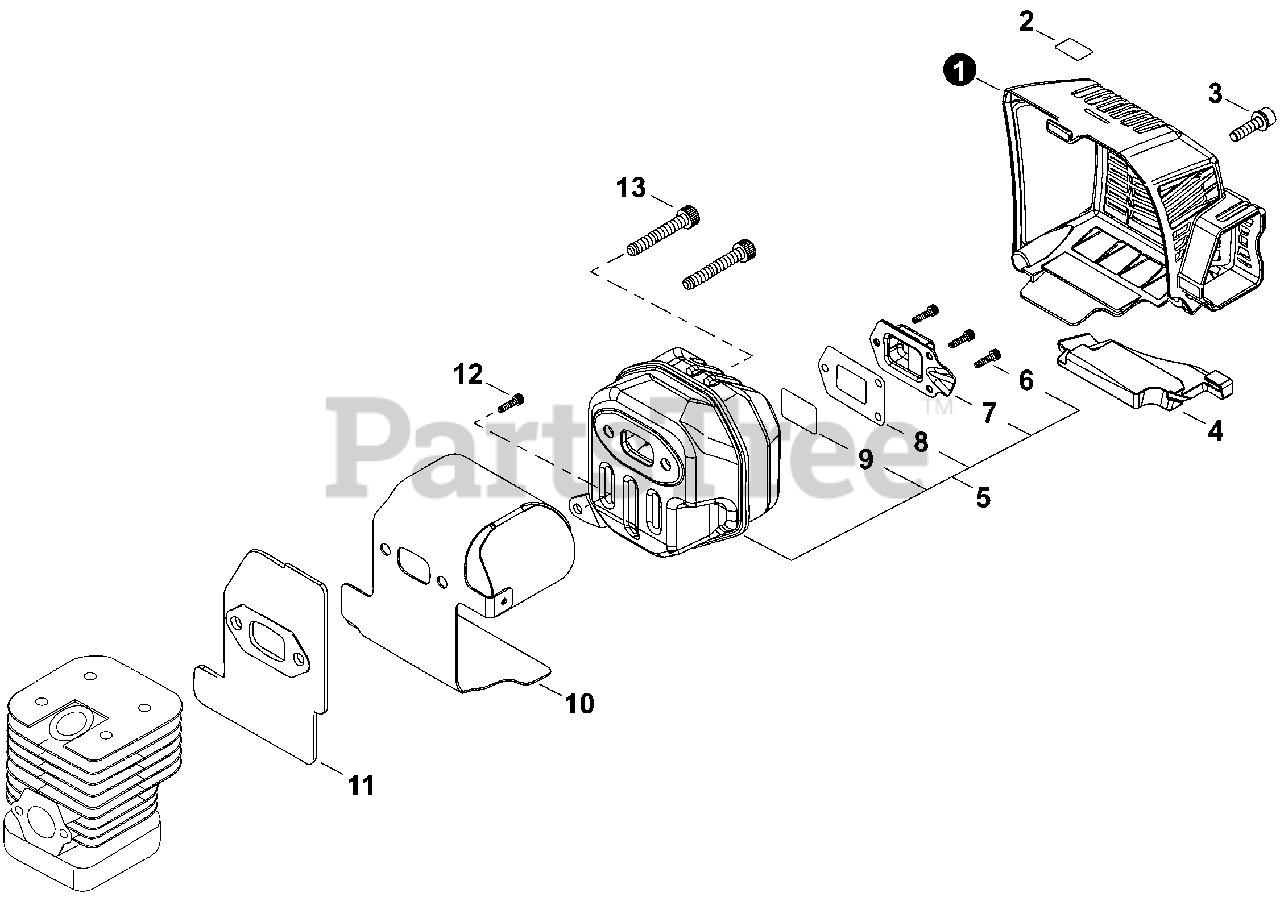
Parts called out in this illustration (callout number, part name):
1	COVER, MUFFLER
2	LABEL - CAUTION - HOT
3	BOLT, TORX 5x25
5	MUFFLER ASSY
6	BOLT, TORX 4x8
7	GUIDE, EXHAUST
8	GASKET, EXHAUST
9	SCREEN, SPARK ARRESTER
10	HEAT SHIELD, EXHAUST
11	GASKET, EXHAUST
12	BOLT, TORX 5x16
13	BOLT, TORX 6x20
